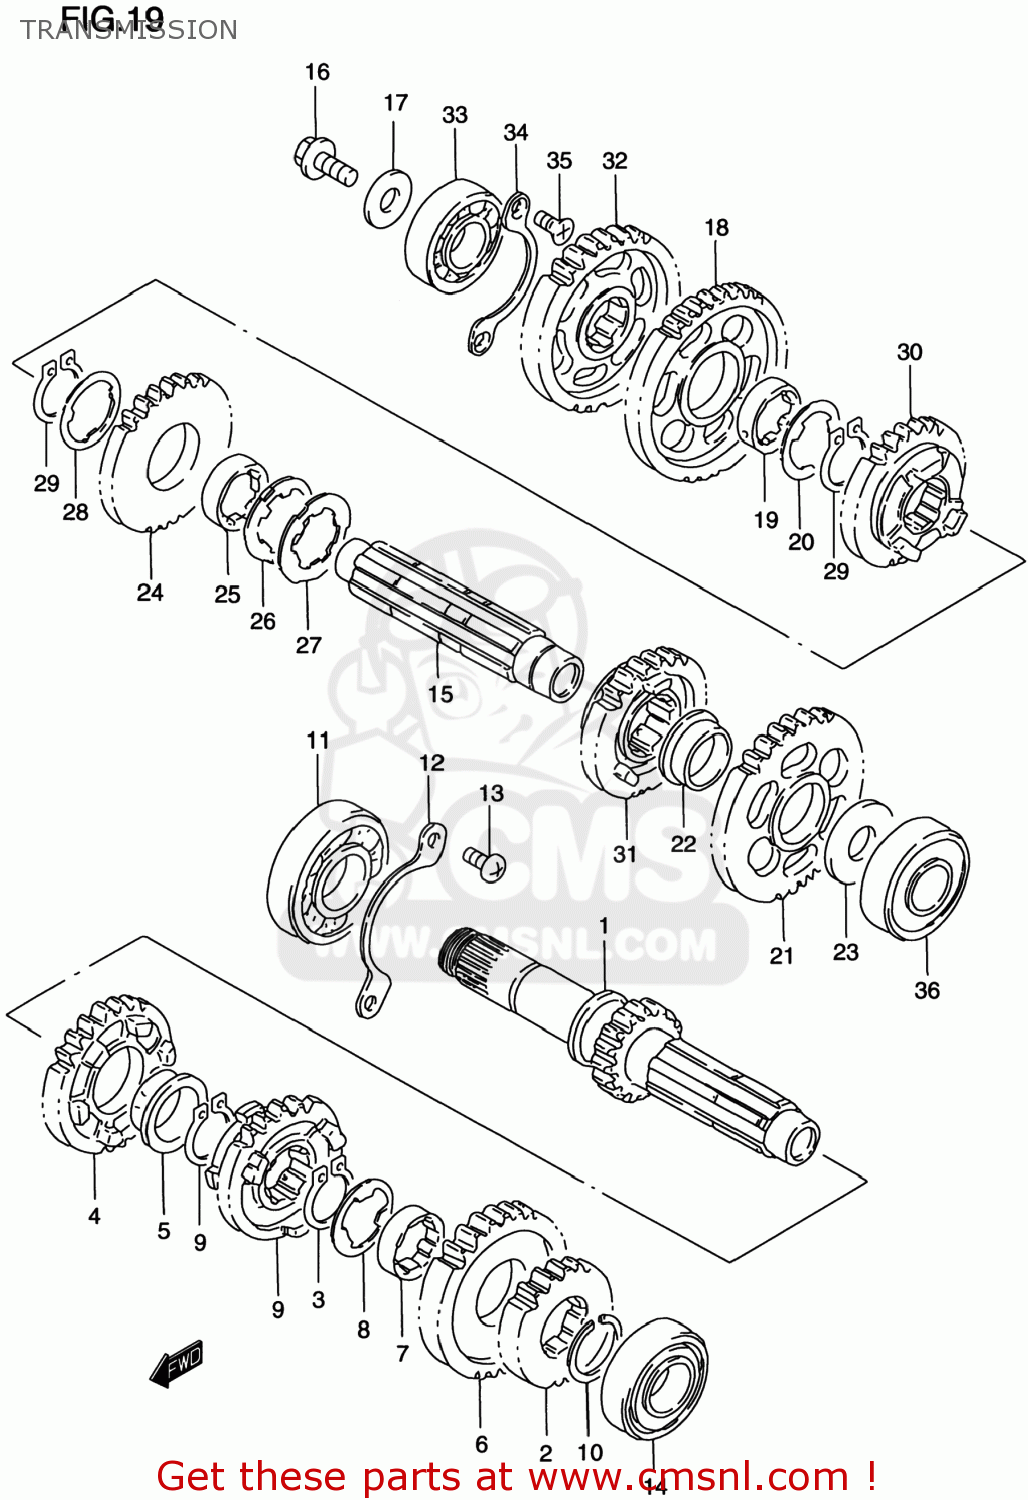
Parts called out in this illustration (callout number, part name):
1	COUNTERSHAFT(NT:14)
2	GEAR,2ND DRIVE(NT:19)
3	GEAR,3RD DRIVE(NT:22)
4	GEAR,4TH DRIVE(NT:25)
5	BUSHING
6	GEAR,5TH DRIVE
7	BUSHING
8	WASHER,LOCK
9	RING,SNAP
10	CIRCLIP
11	BEARING(25X62X17)
12	RETAINER,CNTR SHAFT BEARING
13	SCREW
14	BEARING 20X47X14
15	SHAFT,DRIVE
16	NOZZLE,DRIVE SHAFT
17	WASHER
18	GEAR,1ST DRIVEN(NT:32)
19	BUSH
20	WASHER,LOCK
21	GEAR,2ND DRIVEN(NT:31)
22	BUSH
23	SHIM(20X34X1)
24	GEAR,3RD DRIVEN(NT:27)
25	BUSH
26	WASHER
27	WASHER,LOCK
28	WASHER,LOCK
29	CIRCLIP
30	GEAR,4TH DRIVEN(NT:25)
31	GEAR,5TH DRIVEN
32	GEAR,REDUCTION DRIVE(NT:30)
33	BEARING(20X52X15)
34	RETAINER,DRIVE SHAFT BEARING
35	SCREW
36	BEARING(20X52X15)
